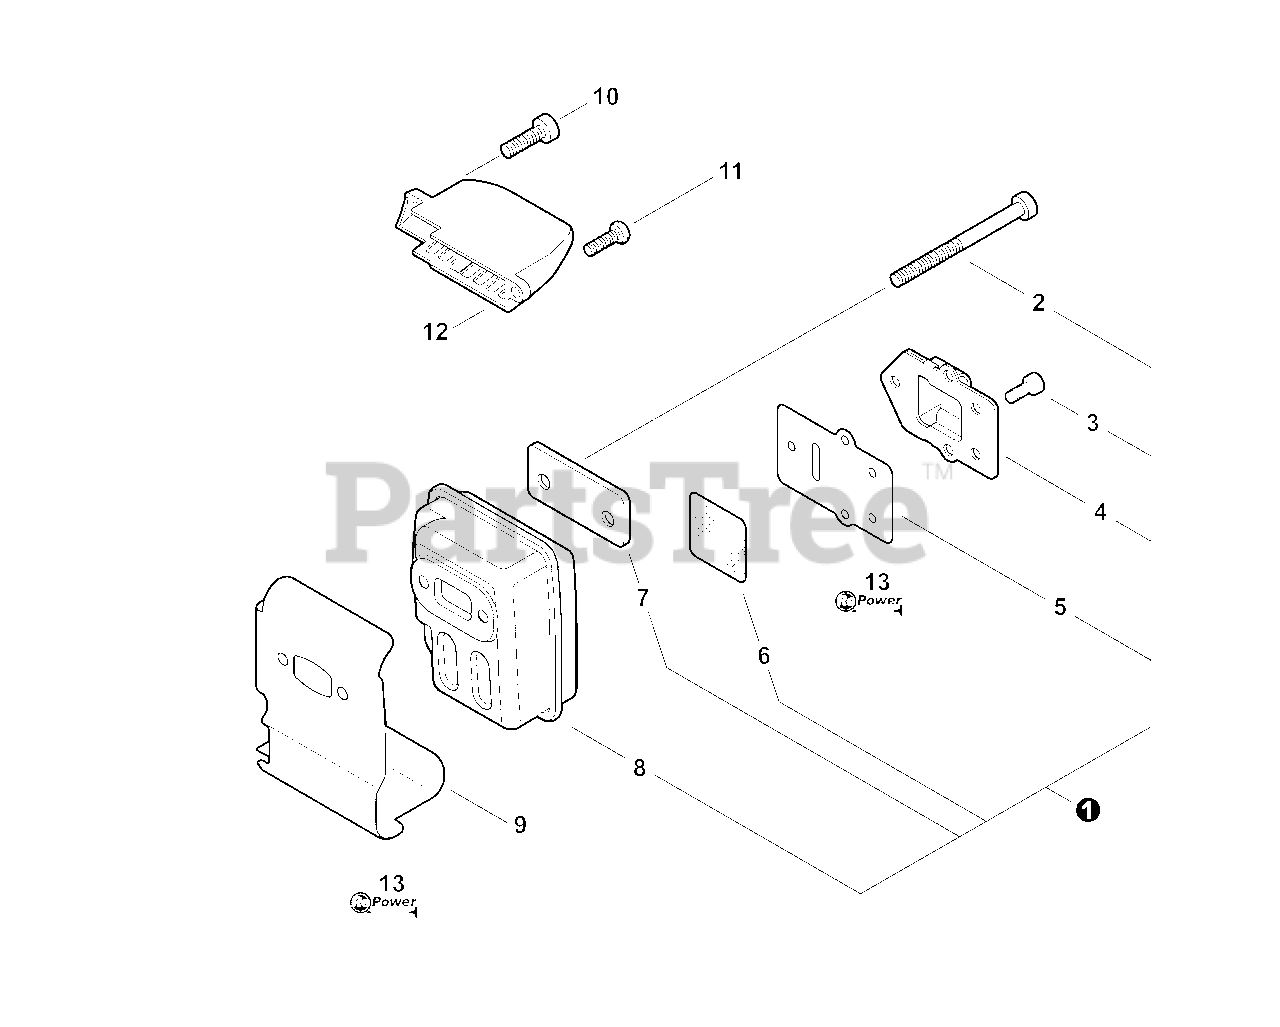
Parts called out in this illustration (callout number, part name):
1	MUFFLER ASSY
2	SCREW - 5×55
3	SCREW - 4×8 -- TORX
4	GUIDE, EXHAUST
5	GASKET, EXHAUST
6	SCREEN, SPARK ARRESTER
8	MUFFLER
9	SHIELD, EXHAUST
10	SCREW - 5×16
11	SCREW - 5×16
12	DUCT, AIR
13	GASKET KIT
